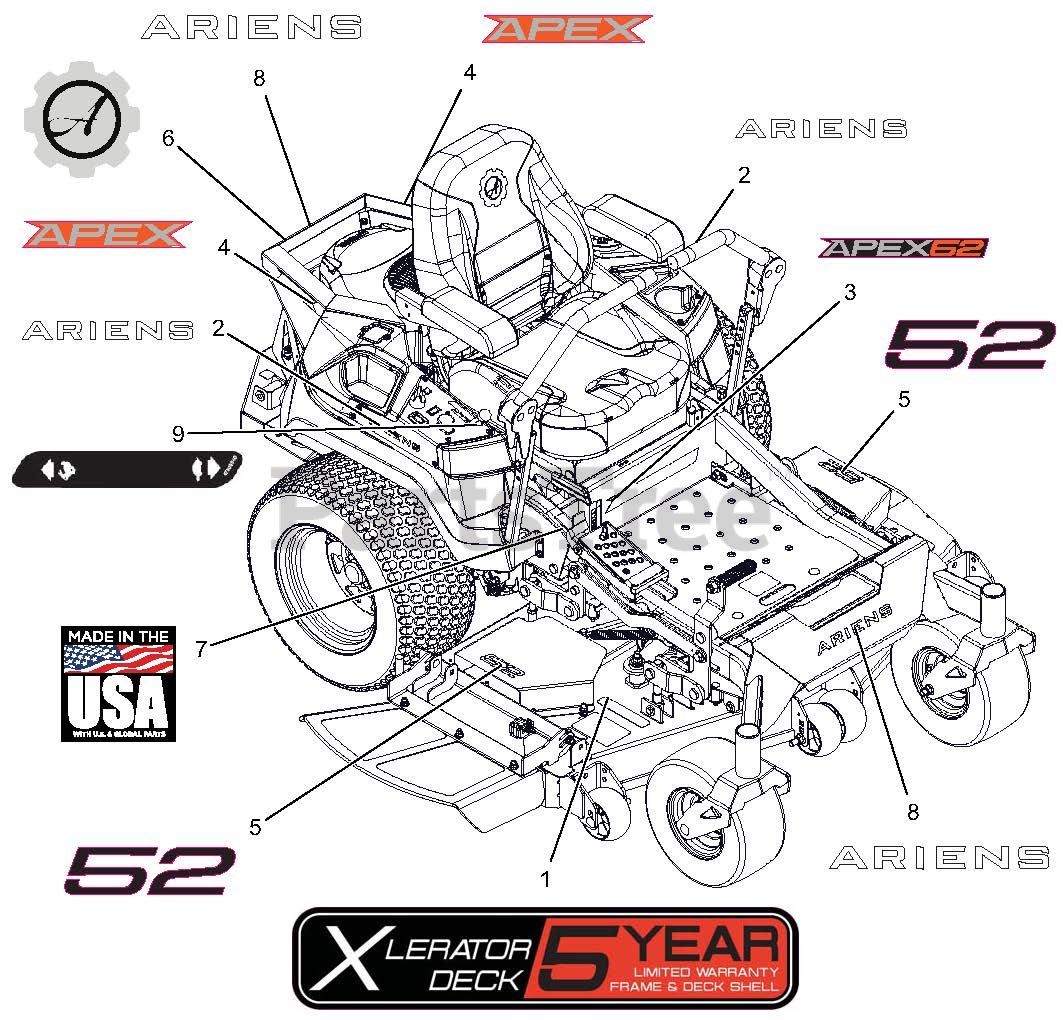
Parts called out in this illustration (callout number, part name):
1	DECAL-ARIENS, DECK 5 YEAR
2	DECAL, ARIENS (6.50")
3	DECAL, 52" APEX KICKPLATE
4	DECAL, APEX FENDER
5	DECAL, BLACK 52
6	DECAL, ARIENS-GEAR BADGE -THK
7	DECAL, MADE IN USA
8	DECAL - ARIENS 9.625"
9	DECAL, DASH DECAL
